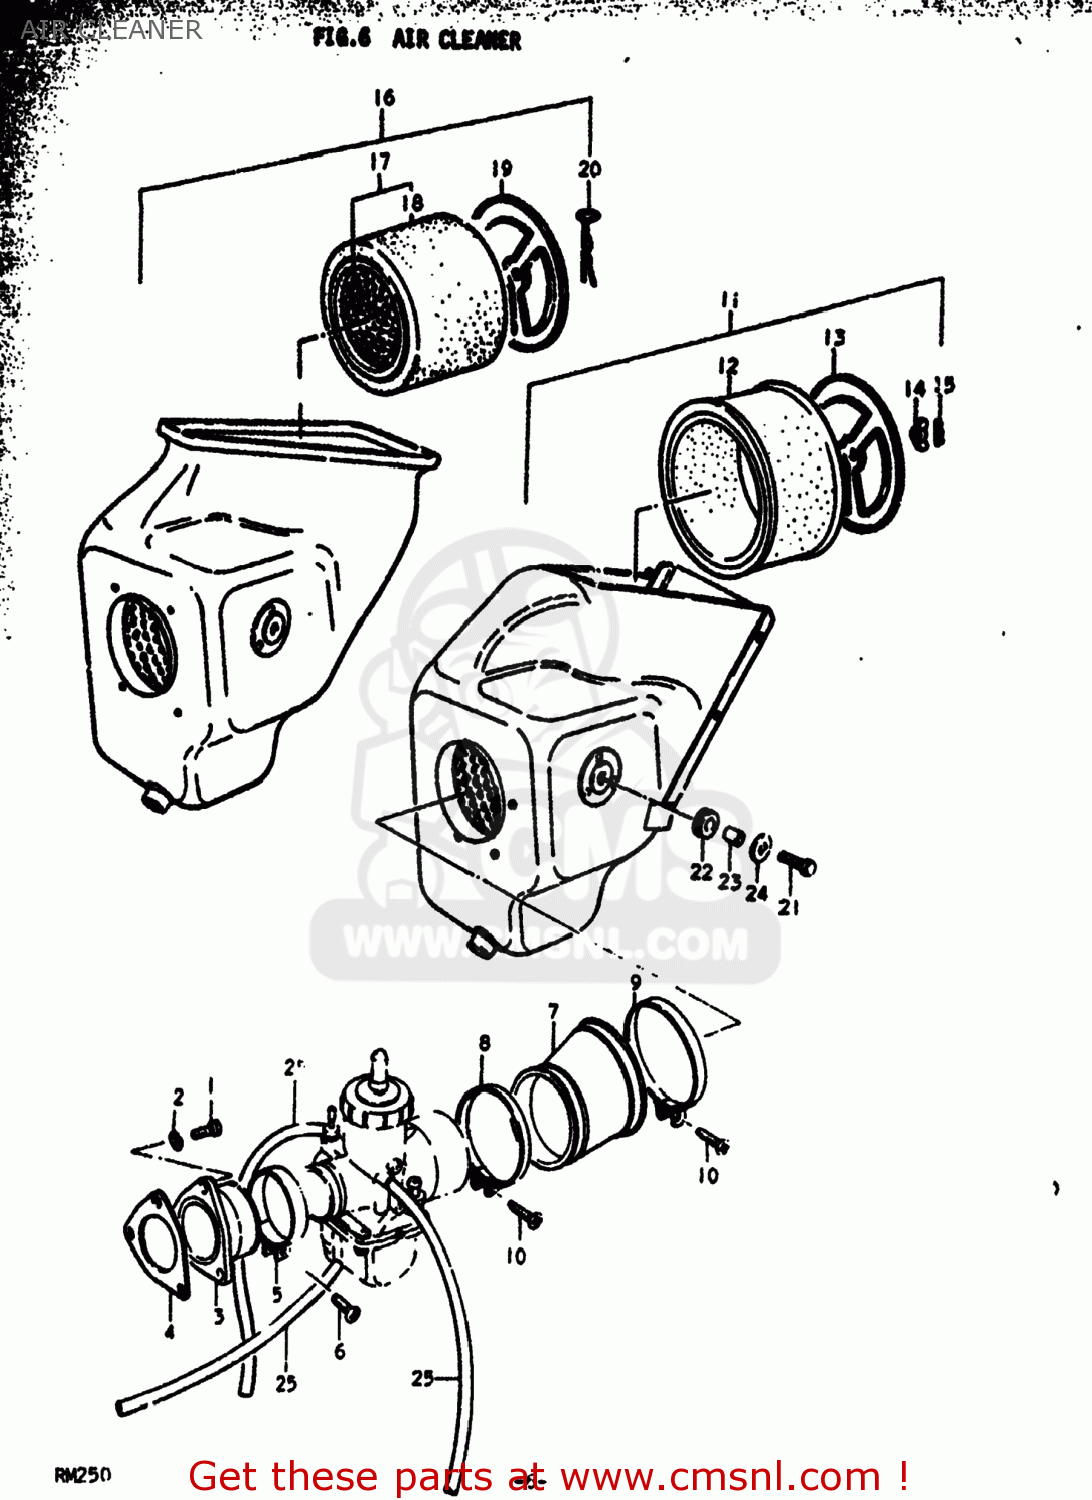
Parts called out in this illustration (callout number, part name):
1	BOLT, UPPER
2	LOCK WASHER
3	PIPE,INTAKE
4	GASKET,INTAKE PIPE (NAS)
5	CLAMP
6	SCREW 5X20
7	TUBE,AIR CLEANER OUTLET
8	CLAMP
9	CLAMP
10	SCREW
11	CLEANER ASSEMBLY,AIR
12	ELEMENT,AIR CLEANER
14	NUT
16	CLEANER ASSEMBLY,AIR
17	FILTER ASSY
18	FILTER
19	CAP
20	SPRING,AIR CLEANER
21	BOLT, UPPER
22	CUSHION
23	SPACER (7X9X7)
24	WASHER (6.5X20X1.2)
25	HOSE
